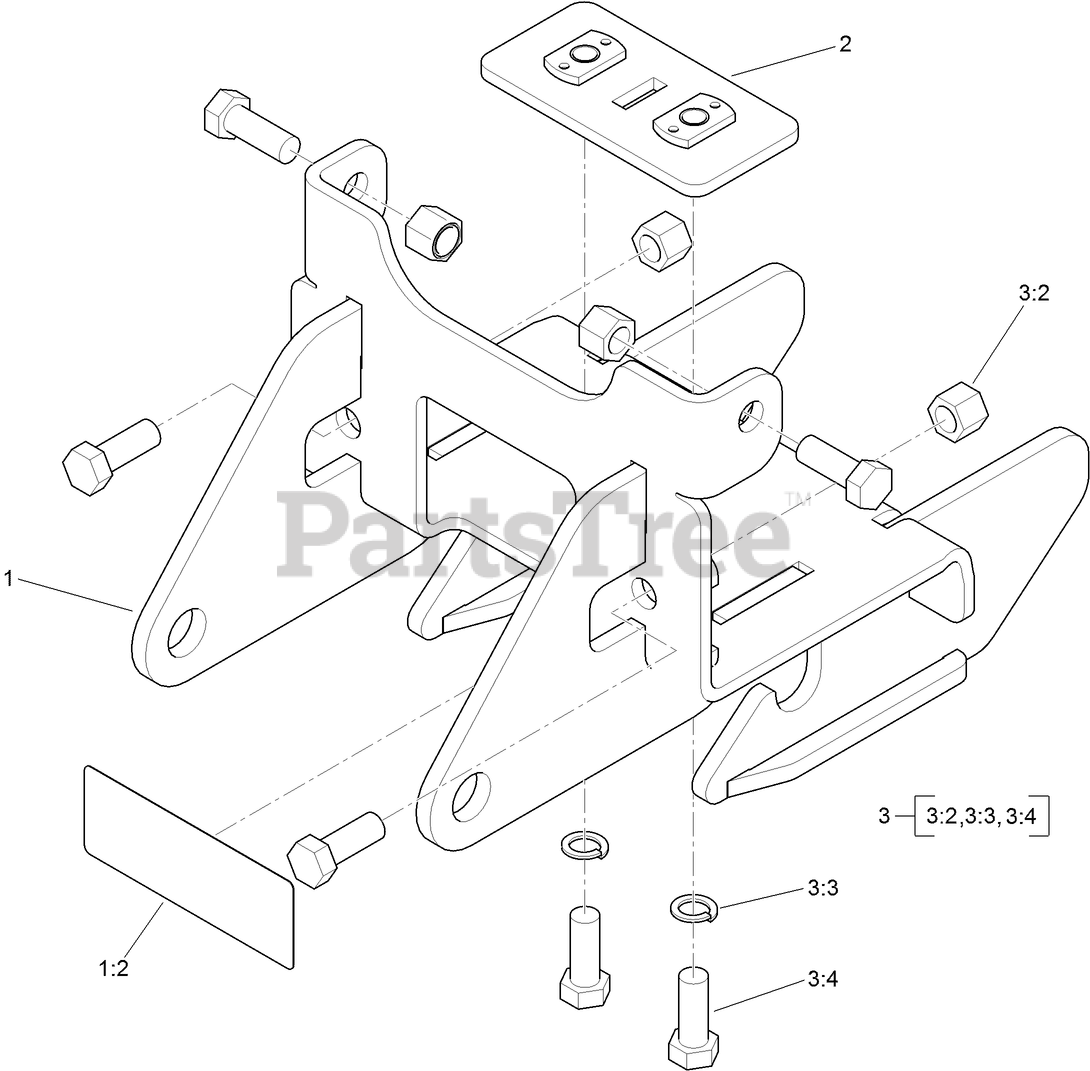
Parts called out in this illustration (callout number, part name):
1	SKID PLT ASM,UC,TORO MDX
1:2	DECAL,UC LOGO,ATV/UTV
2	NUT PLT WDMT,UC,TORO MDX
3	HDW KIT,UC,TORO MDX
3:2	NUT,3/8-16,NYL INS,YZN
3:3	WASHER,3/8,SPLIT LOCK,YZN
3:4	HHCS,3/8-16X1 NC GR5 PLT
